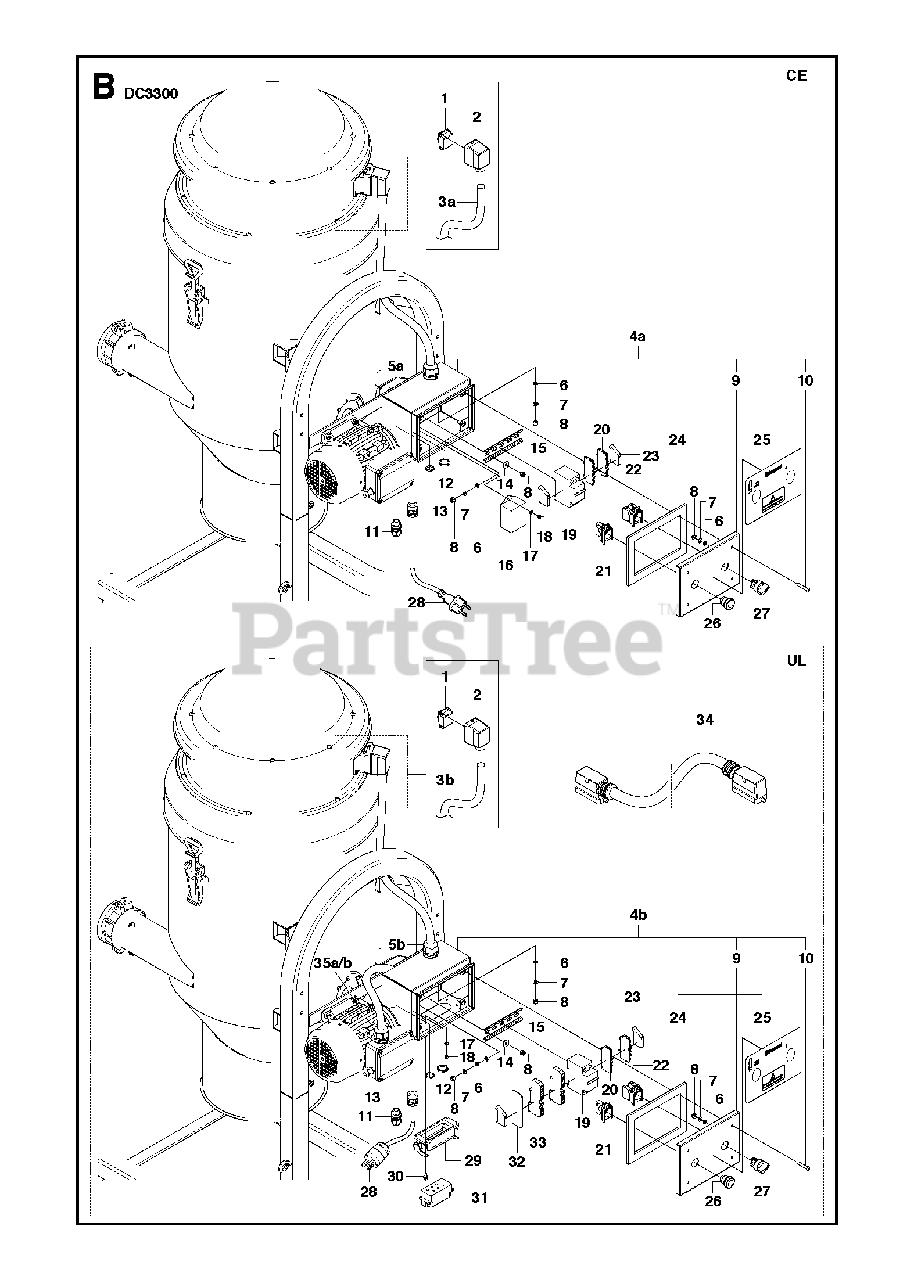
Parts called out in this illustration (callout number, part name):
8	HEXAGON LOCKING NUT
18	HEXAGON LOCKING NUT
30	SCREW CRPANM
